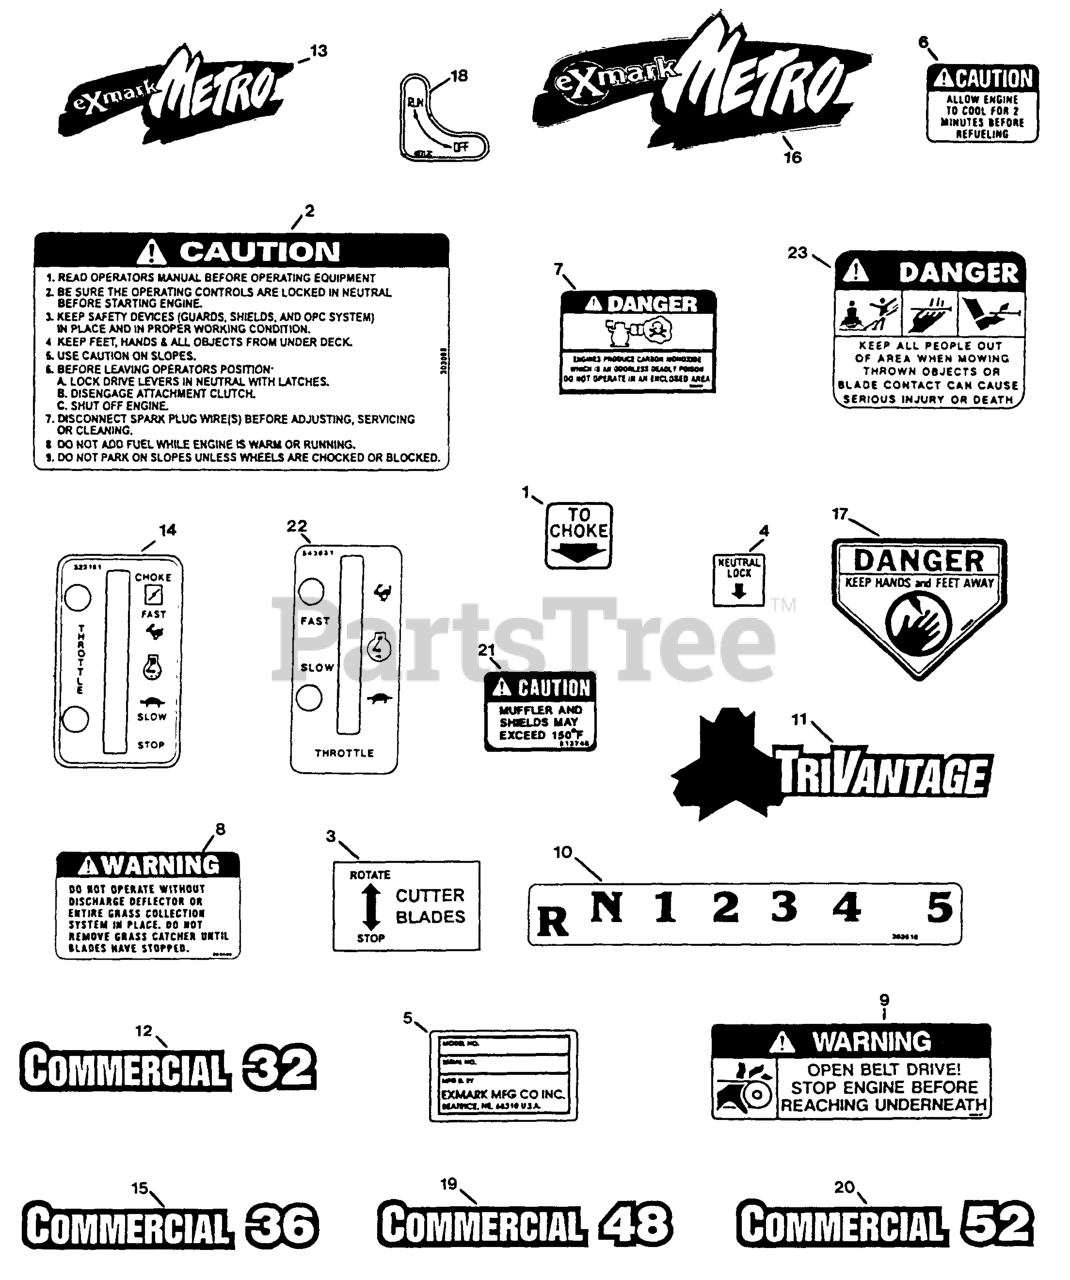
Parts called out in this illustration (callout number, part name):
2	LABEL,INSTRUCTION
3	DECAL,CUTTER BLADE
4	DECAL,NEUTRAL LOCK
8	DECAL-WARNING, DISCHARGE
9	DECAL,BELT DRIVE
10	DECAL,SHIFTER
12	DECAL,COMMERCIAL 32
15	DECAL,COMMERCIAL 36
17	DECAL-DANGER
19	DECAL,COMMERCIAL 48
20	DECAL,COMMERCIAL 52
23	DECAL-DANGER
